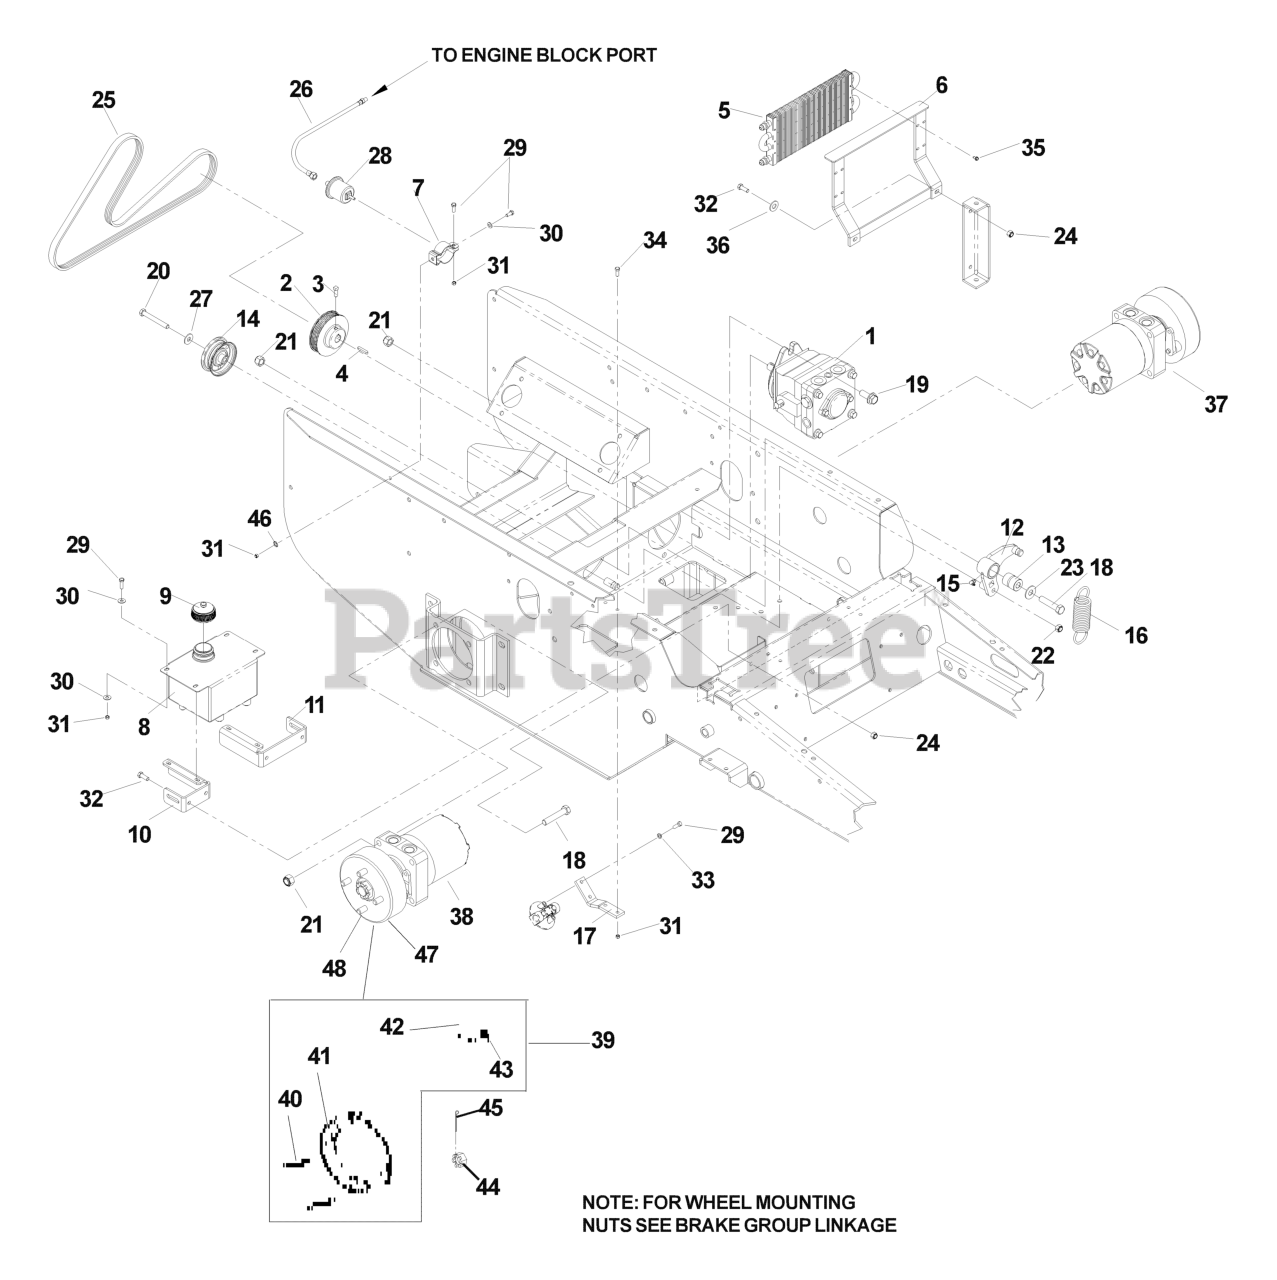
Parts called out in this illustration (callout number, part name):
1	HG_PUMP CCW RH
2	PUMP SHEAVE
3	SCREW 5/16C X 1 SQ HEAD SET
4	KEY, METRIC
6	COOLER WLDMT MT
7	CLAMP-OIL SENDER
8	TANK, OIL = PAINTED
9	HYDRAULIC CAP
10	TANK MOUNT RT
11	TANK MOUNT LT
12	ARM WELDMENT
14	IDLER PULLEY
17	FILTER MOUNT - PAINTED
18	HEX SCREW 1/2-13 X 2.5" GR 5
19	HCS 1/2C X 1 1/4 SERRATED HEAD
20	HCS 3/8C X 3
21	NUT 1/2-13 HEX NYLOC ZD
22	NUT 3/8-16 NYLOC
23	WASHER 1/2 FLAT
24	NUT 5/16 NYLOC
27	WASHER 3/8 SAE FLAT
28	SENDER,OIL PRESS
29	HCS 1/4C X 3/4 HCS
30	WASHER 1/4 FLAT
31	NUT.1/4-20.HEX.NYLOC.ZD
32	HCS 5/16C X 1
33	LOCKWASHER 1/4"
34	HCS 1/4 X 1
35	SCR #10-12X3/4 HEX WAS HD ZD
36	WASHER 5/16 FLAT
37	WHEEL MTR ASM
38	WHEEL MTR ASM, RT
39	SHOE ASM.
40	RETURN SPRING
44	CASTLE-NUT
45	COTTER PIN
46	WASHER 1/4 EXTLW STAR ZD
48	WHEEL STUD 1/2-20X1-3/8 GR8 ZN
